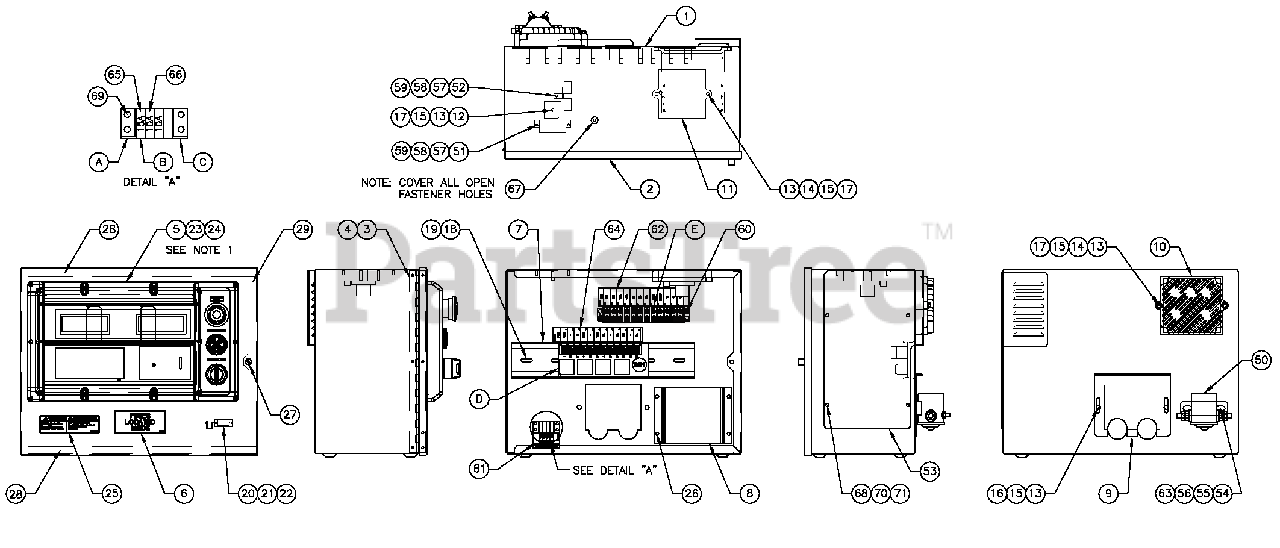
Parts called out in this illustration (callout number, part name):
1	ENCLH/G CONTROL PANEL
2	COVER CONTROL PANEL
3	HINGE CONTINUOUS H PANEL
4	RIVET POP .125X .275SS
5	ASSYPROGRAMMEDH-100
6	DECAL FUSES LOCATED INSIDE
7	RAILSNAPTRACK PCB HOLDER BULK (12" LG)
8	ASSYPCB 2AMP 12V ULBATTCHGR
9	PLATE HARNESS CLAMP
10	ASSYPCB PWRAVRW/AMP HEADER
11	ASSYPCB BOSCH GOV DRIVER
12	DIO BRIDGE25A 600V
13	WASHER LOCK M5
14	SCREW PPHM M5-0.8X 30SS
15	WASHER FLAT M5
16	SCREW HHPM M5 0.8X12
17	NUT HEXM5 0.8G8 YELCHR
18	WASHER FLAT M4
19	SCREW PHTT M40.7X 10ZYC
20	CONN DUST CAP W/CHAIN DB9
21	WASHER FLAT M3.5
22	SCREW PHTT M3.5 0.6X 10
23	SCREW PPHM M4-0.7X 8 BLXOX
24	WASHER LOCK #8 M4
25	DECAL WRNB ATT CHRG12/24VBI
26	SCREW PHTT M40.7X 12ZYC
27	M5 0.8 CAPTIVE PANEL KNLDHD
28	SEAL COVER 3.18 X 12.7X 382
29	SEAL COVER 3.18 X 12.7X 283
50	RELAY CONTACTOR 12VDC
53	COVER CONTROL PANEL SIDE
54	SCREW HHC 1/4-20X3/4G5
55	WASHER FLAT M6-1/4
56	WASHER LOCK M6-1/4
57	WASHER LOCK M3
58	NUT HEXM3 0.5G8 YELCHR
59	WASHER FLAT M3
60	SCREW PHTT#6-32X5/8ZYC
61	DECAL CPL CONTROL PANEL FUSES
62	DECAL CPL 5.4/6.8LTB3
63	NUT HEX 1/4-20 STEEL
64	DECAL CPL 5.4/6.8L RELAY BOARD
65	FUSE ATO TYPE 15 AMP (BLUE)
66	FUSE ATO TYPE 10 AMP (RED)
67	SEAL WEATHER.45"DIA
68	SCREW PPHM M5-0.8X 12ZNC
69	SCREW PHTT#6-32X3/8ZYC
70	WASHER FLAT M5
71	WASHER LOCK M5
A	ADPTR RH SIDE WICKMANN 178.6191
B	HOLDERFUSE WICKMANN 178.6150
C	ADPTR LH SIDE WICKMANN 178.6192
D	ASSYPCB G PANEL RELAY 12VDC
E	BLOCK TERM 20A 12X 6 X1100V
